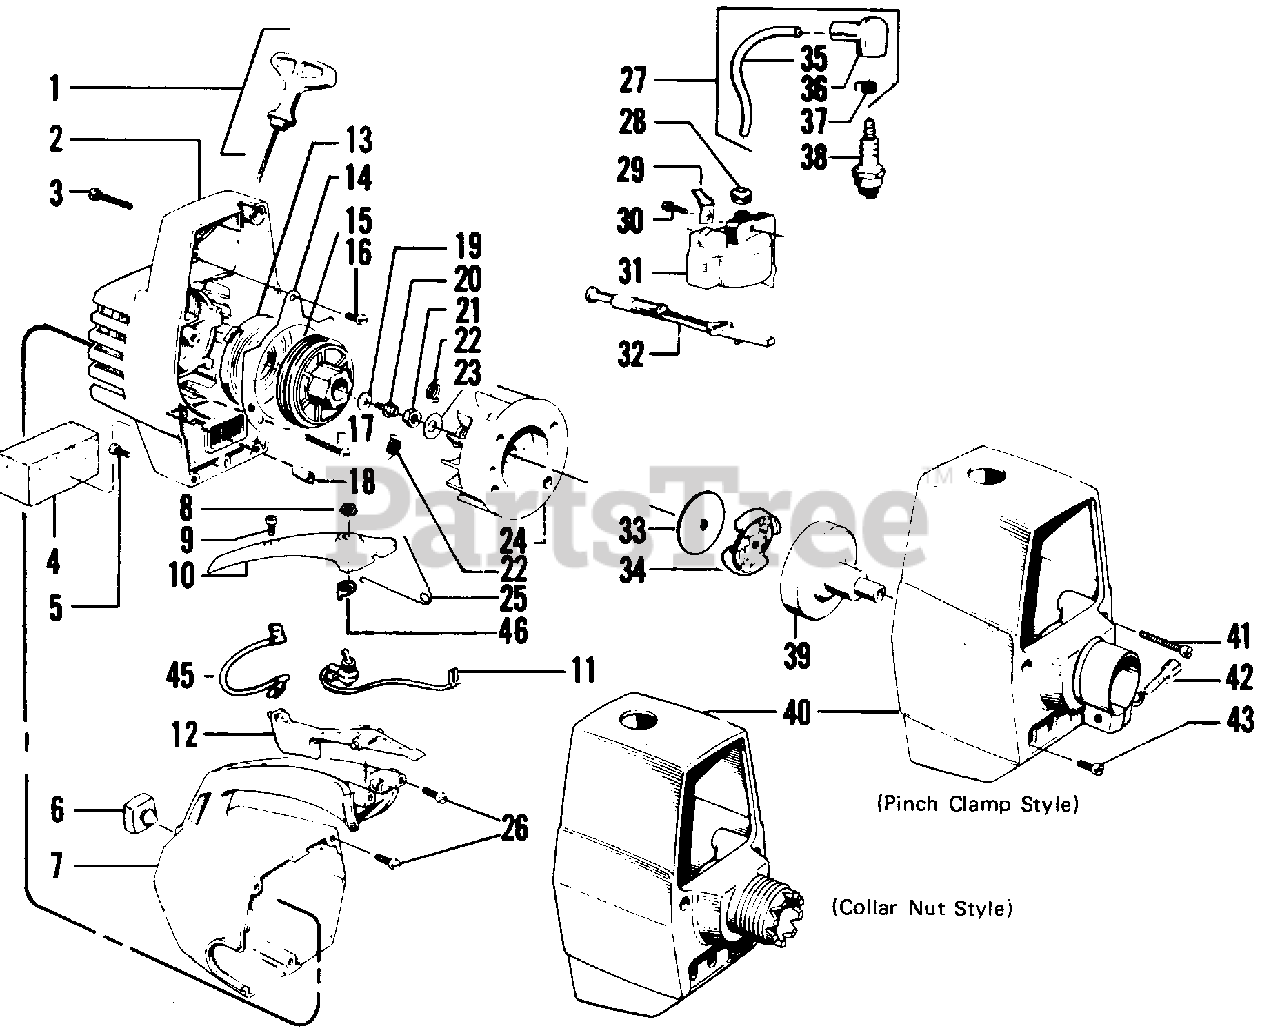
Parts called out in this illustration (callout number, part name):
2	Fan Hsg. Kit (Inc. 14,16,17,18)
3	Screw - #10 - 24 x 1-1/2" - Fan Hsg. Top
4	Air Filter
5	Screw - #10 - 24 x 5/8" - Fan Hsg. Bottom
6	Bumper - Fuel Tank Housing
7	Handle & Fuel Tank Housing
8	Nut - Grounding Switch
9	Screw - #8 - 16 x 3/4" - Handle Cover
10	Handle Cover
11	Grounding Switch Kit (Inc. 8,29,45,46)
12	Trigger - Throttle
14	Air Baffle
16	Screw - #10 - 24 x 1/4" - Fil. Hd. - Air Baffle
17	Screw - #10 - 24 x 1-3/16" -Fil. Hd. - Air Baffle
19	Washer - Starter Pulley
20	Screw - #10 - 24 x 1/2" - Starter Pulley
21	Nut - #5/16 - 24" - Flywheel
22	Spring - Starter Dog
23	Washer - Flywheel
24	Flywheel Assembly (Inc. 22)
25	Trigger - Spring
26	Screw # 10 - 24 x 3/4" - Fan Housing to Handle & Fuel Tank
27	High Tension Lead Assembly (Inc. 35, 36 & 37)
28	Grommet - Plug Wire
29	Electrical Tab 45ø
30	Screw - #8 - 32 x 3/4" - Ignition Module
31	Kit - Module - Ignition
32	Choke Knob
33	Kit - Clutch Washer
34	Kit - Clutch Ass'y (Incl. Washer) - See Service Ref. 1 and 5.
35	High Tension Lead Wire
36	Boot - Spark Plug
37	Connector - Spark Plug Lead
38	Spark Plug (Champion CJ-14)
39	Drum - Clutch and Drive Adaptor
40	Shroud
40	Collar Nut Style
40	Pinch Clamp Style
41	Screw - #10 - 24 x 1-1/2" - Shroud Top
42	Bolt - #1/4 - 20 x 1" Hex - Pinch Clamp
43	Screw - #10 - 24 x 5/8" Fil. - Shroud Bottom
45	Wire - Lead - Grounding Switch
46	Washer - Grounding Switch
